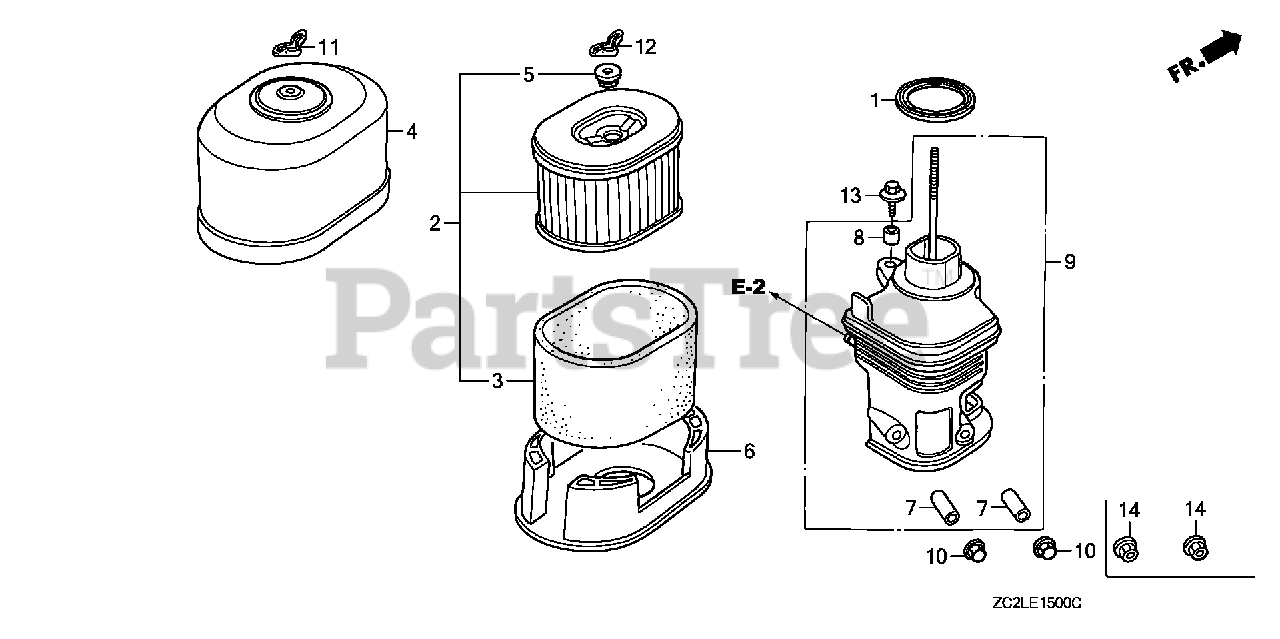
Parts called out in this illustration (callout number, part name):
1	GASKET, ELBOW
2	ELEMENT, AIR CLEANER
3	FILTER (OUTER)
4	COVER, AIR CLEANER (STD)
5	GROMMET, AIR CLEANER
6	NOSE, MUFFLER
7	COLLAR, AIR CLEANER
8	COLLAR B, AIR CLEANER
9	ELBOW, AIR CLEANER
10	NUT, CAP (6MM)
11	NUT, AIR CLEANER COVER (DACRO COATING)
11	WINGNUT (6MM) (BLACK)
11	NUT, TOOL BOX SETTING
12	NUT, TOOL BOX SETTING
13	BOLT-WASHER (6X20)
14	NUT, FLANGE (6MM)
